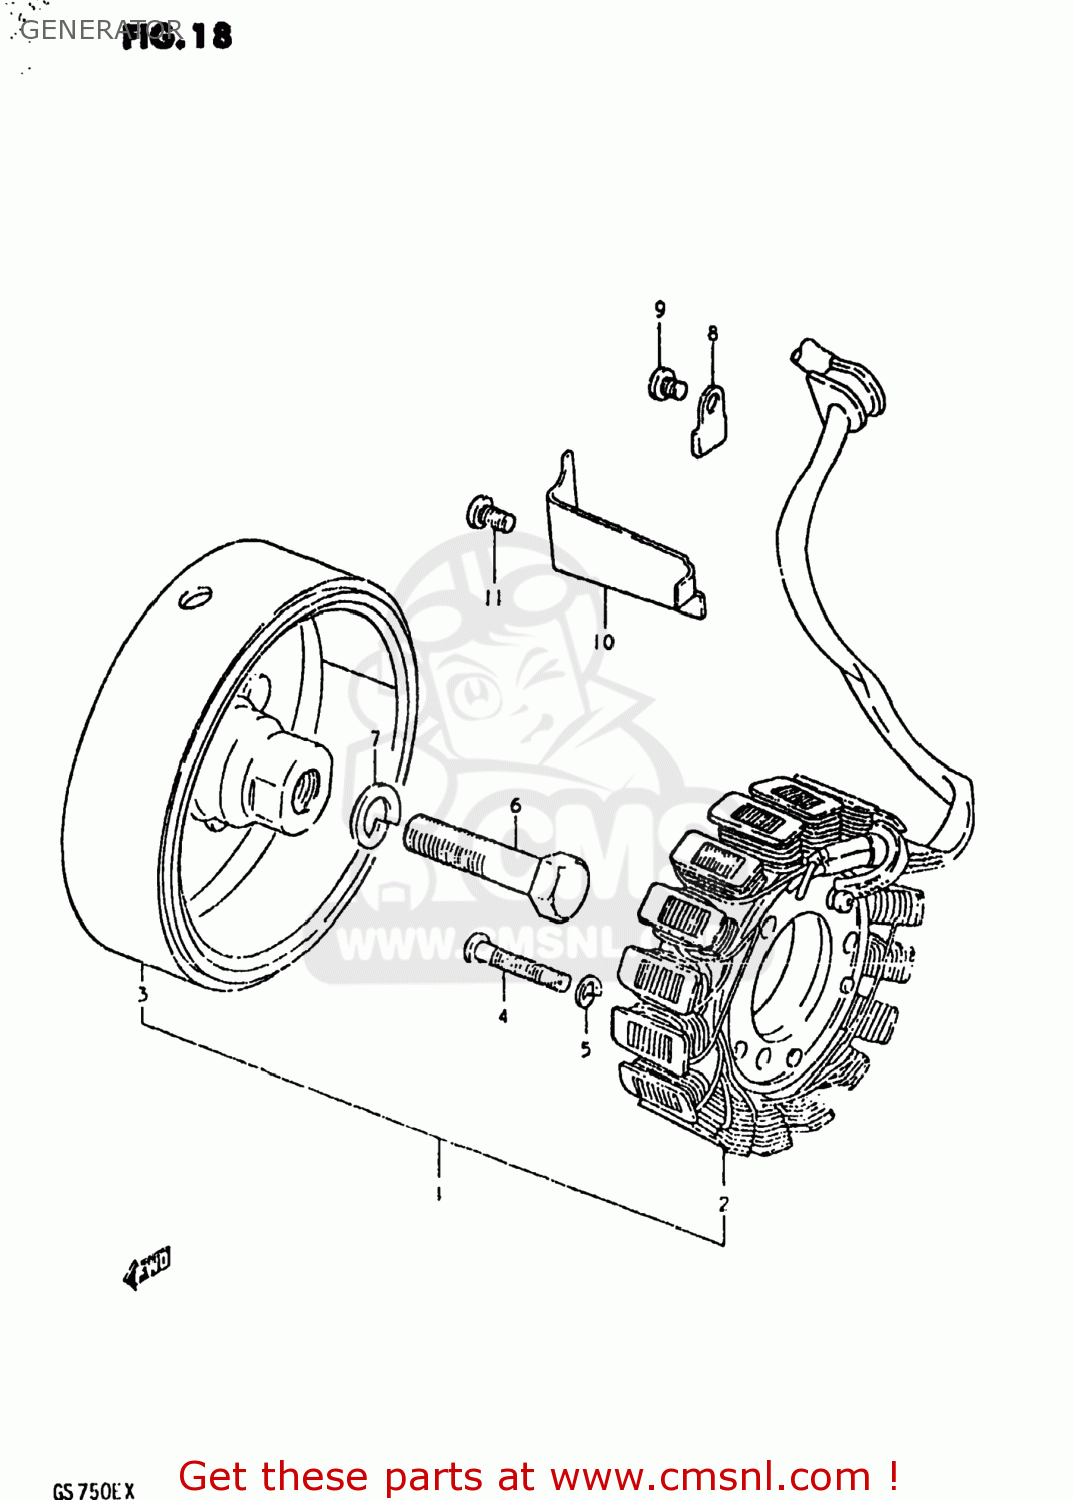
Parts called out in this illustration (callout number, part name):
1	GENERATOR ASSEMBLY
2	STATOR ASSEMBLY
3	ROTOR ASSEMBLY
4	SCREW
5	LOCK WASHER
6	BOLT 12X45
7	WASHER,LOCK 12
8	CLAMP,GENERATOR LEAD WIRE
9	SCREW
10	CLAMP,GENERATOR LEAD WIRE
11	SCREW
